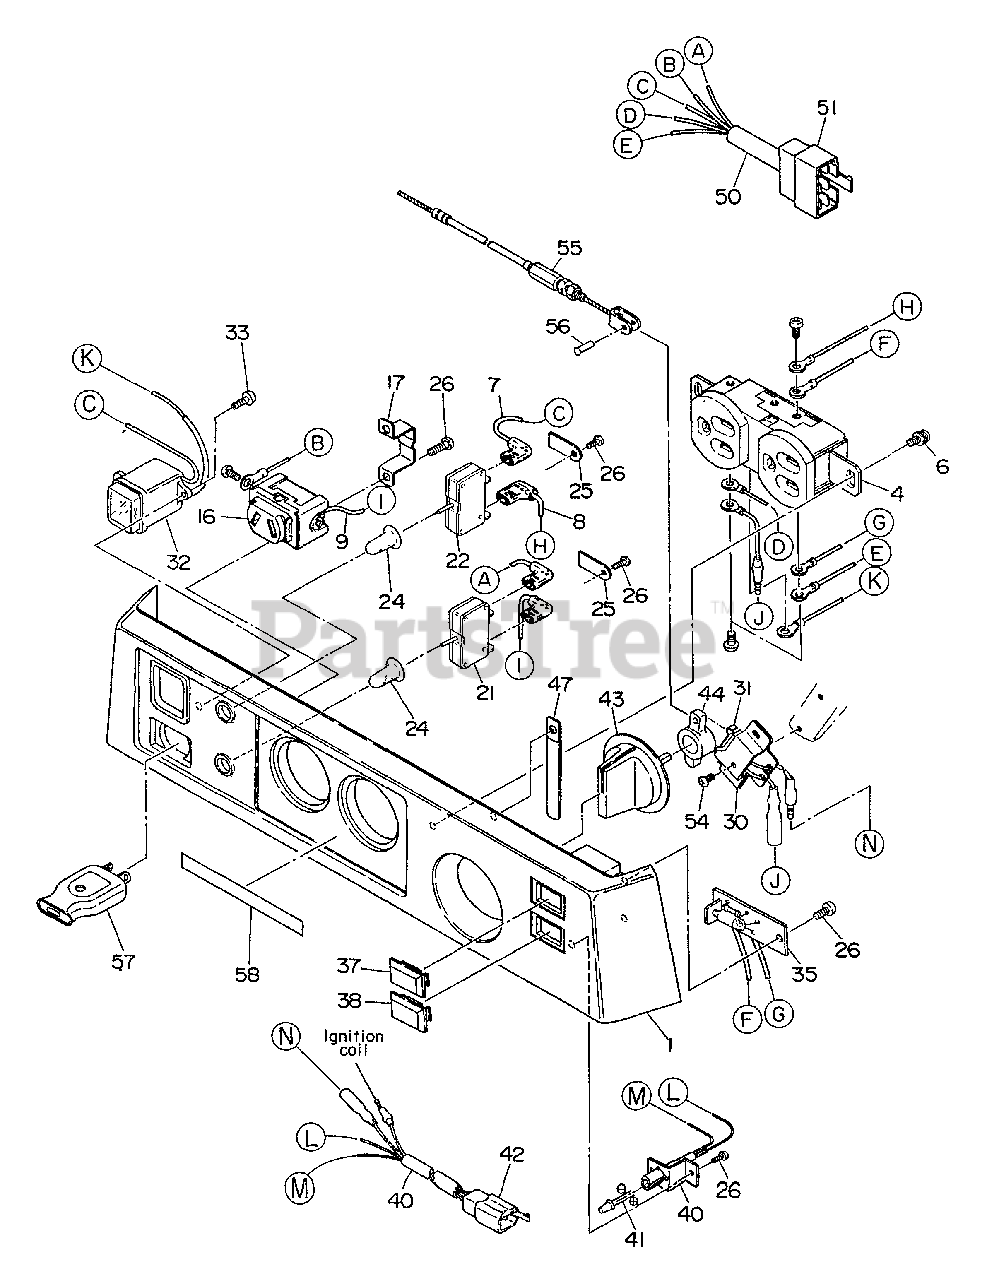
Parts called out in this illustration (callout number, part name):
1	CONTROL PANEL ASSY
1	PANEL
4	AC RECEPTACLE
6	SCREW
7	WIRE - 19
8	WIRE - 20
9	WIRE - 5
16	DC RECEPTACLE
17	CLAMP
21	CIRCUIT BREAKER - 10A
22	CIRCUIT BREAKER - 3.5A
24	CAP
25	CLAMP
26	SCREW -- TAPPING
30	MICRO SWITCH ASSY
31	MICRO SWITCH
32	VOLT METER
33	SCREW -- TAPPING
35	LAMP
37	CAP - GREEN
38	CAP - CLEAR
40	WIRE HARNESS ASSY
41	LED
42	CONNECTOR
43	KNOB
44	LEVER
47	CLAMP
50	WIRE HARNESS
51	CONNECTOR
54	SCREW
55	CHOKE WIRE ASSY
56	SCREW
58	LABEL -- HZ-V
